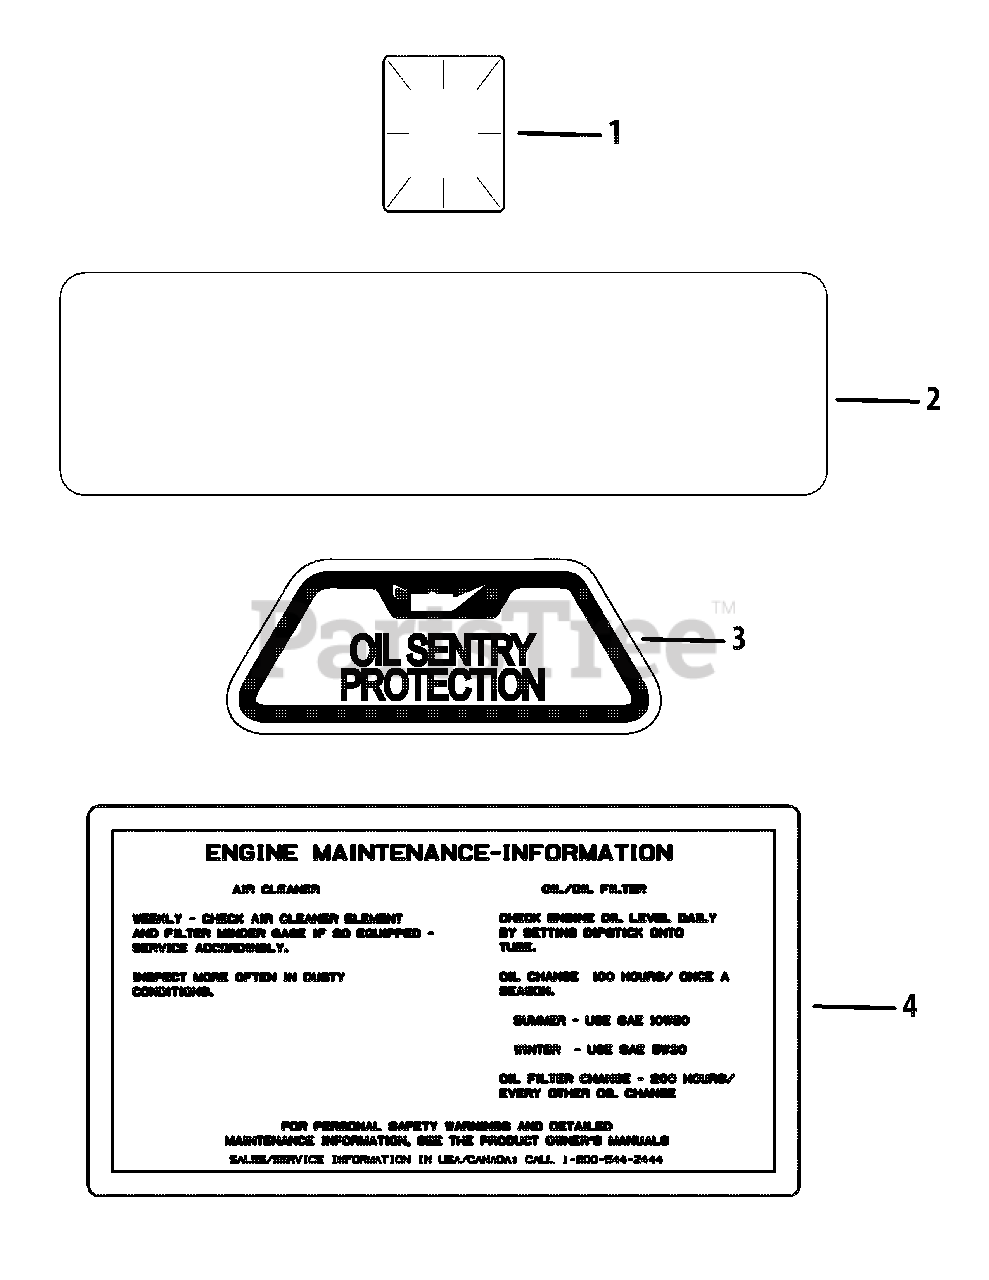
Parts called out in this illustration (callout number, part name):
1	Clear Laminate Decal
2	Command 27 HP Decal
3	Oil Sentry Decal
4	Air Cleaner Decal
